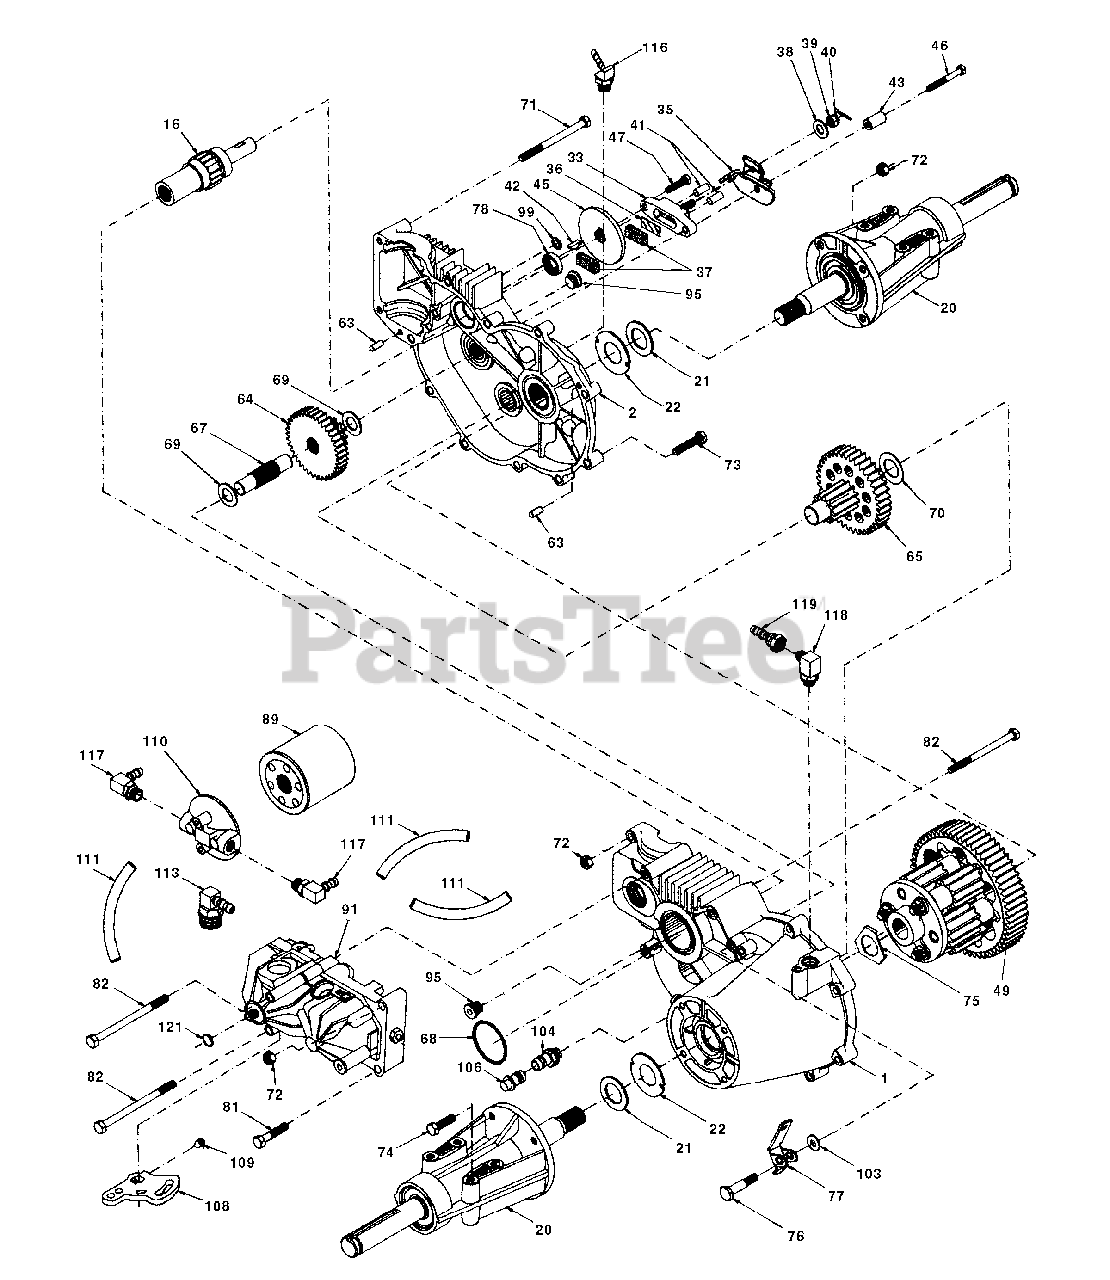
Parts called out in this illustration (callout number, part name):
1	Assembly, Lh Housing
2	Assembly, Rh Housing
16	Brake Shaft Assembly
20	Axle Mounting Horn Ass'y
21	Washer,1.0x1.63x.08
22	Washer,1.0x2.06x.09
33	Brake Yoke Assembly
36	Puck Plate
37	Brake Puck
38	Washer,7/8odx7/16x.060
39	Castle Nut, 5/16-24
40	Cotter Pin
41	Brake Actuating Pin
42	Hi Pro Key
45	Brake Disc
46	Bolt, 1/4-20 X 1-1/2
47	Bolt, 1/4-20 X 1
49	Differential Assembly
64	14t-38t Reduction Gear
65	Final Drive Pinion Ass'y
67	Jack Shaft
69	Washer,5/8 X 1-5/32
70	Washer,7/8 X 1-1/2
71	Bolt, Hex 5/16-18 X 3.5
72	Hex Lock Nut, 5/16-18
73	Bolt, Hex 5/16-18 X 1-1/2
74	Hex Cap Screw, 5/16-18 X 1
75	Washer, Differential
76	Shoulder Bolt
77	Freewheel Actuating Arm
78	Oil Seal, .625 X 1.0 X .25
81	Bolt, Hex 5/16-18 X 1-3/4
82	Bolt, 5/16-18 X 4-1/2
89	Spin On Filter
91	Bdu-10l-118
95	Straight Thread Plug
99	Washer, 11/32 X 9/16
104	Cap-Vent Assembly
106	Fitting-O Ring Assembly
108	Control Arm
110	Filter Head
111	Hose, 5/16 X 12" Long
113	90° 7/8 Sae Fitting
116	45° 9/16 Sae Fitting
117	90° 9/16 Sae Fitting
118	90° Sae #6 Flare Male Fitting
119	90° Sae #6 Flare Female Fitting
121	Wire Retaining Ring
